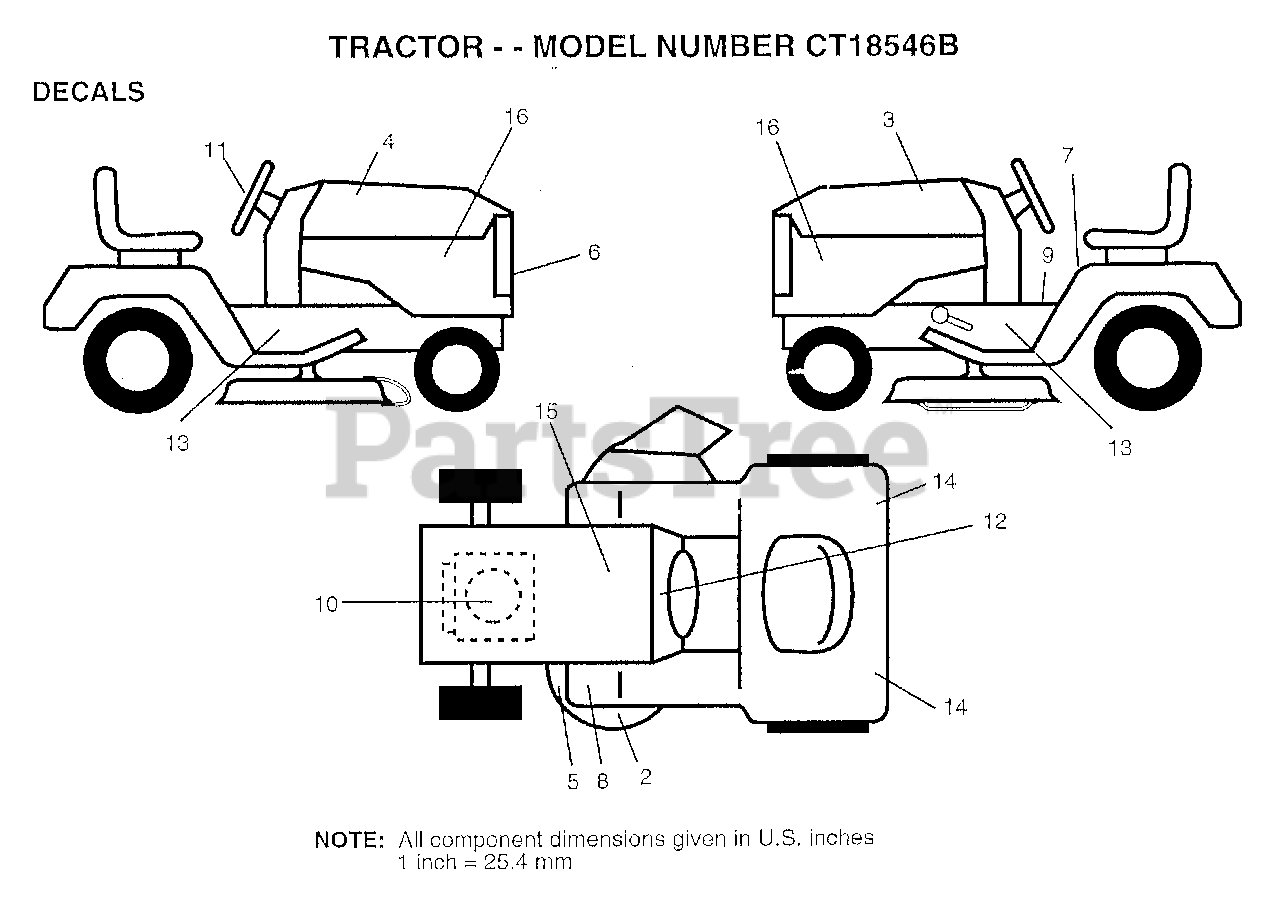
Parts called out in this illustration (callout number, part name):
2	"DECAL,ENVIRO DECK"
3	"DECAL HOOD,LH"
4	DECAL HOOD RH
5	"DECAL.V.BELT.44"""
6	DECAL GRILLE
7	"DECAL DANGER,FEND"
9	DECAL BRAK PARK
10	DECAL, HP, ENGINE
11	DECAL INST STG WH
12	"DECAL-OPER,GEAR D"
13	DECAL CHASSIS
14	REFLECTOR-TAIL YT
15	DECAL.BATRY.3-3908
16	"DECAL PANEL,SIDE"
